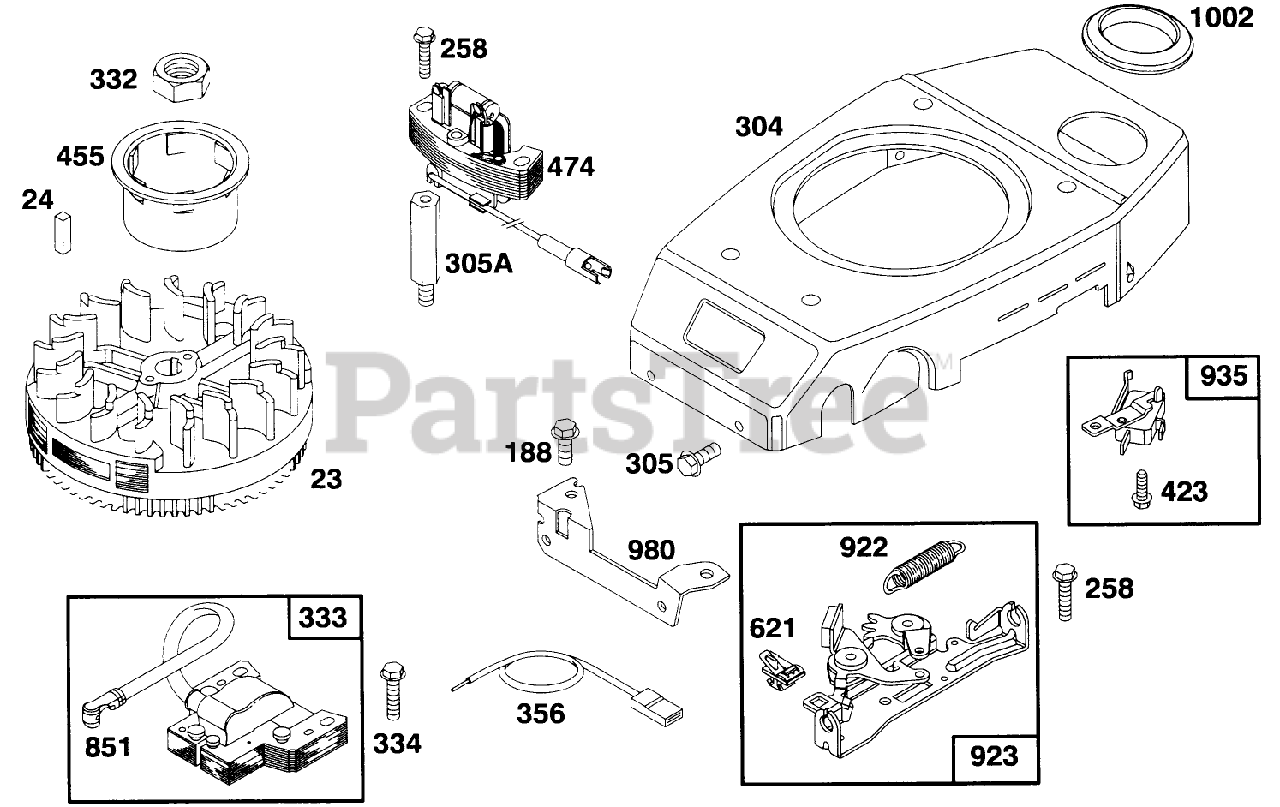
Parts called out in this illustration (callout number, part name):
23	FLYWHEEL - MAGNETO
24	KEY - FLYWHEEL
305	SCREW - HEX HEAD
332	NUT - HEXAGON
334	SCREW - SEM
356	WIRE - GROUND
621	STOP SWITCH
980	BRACKET-BLOWER HSG
